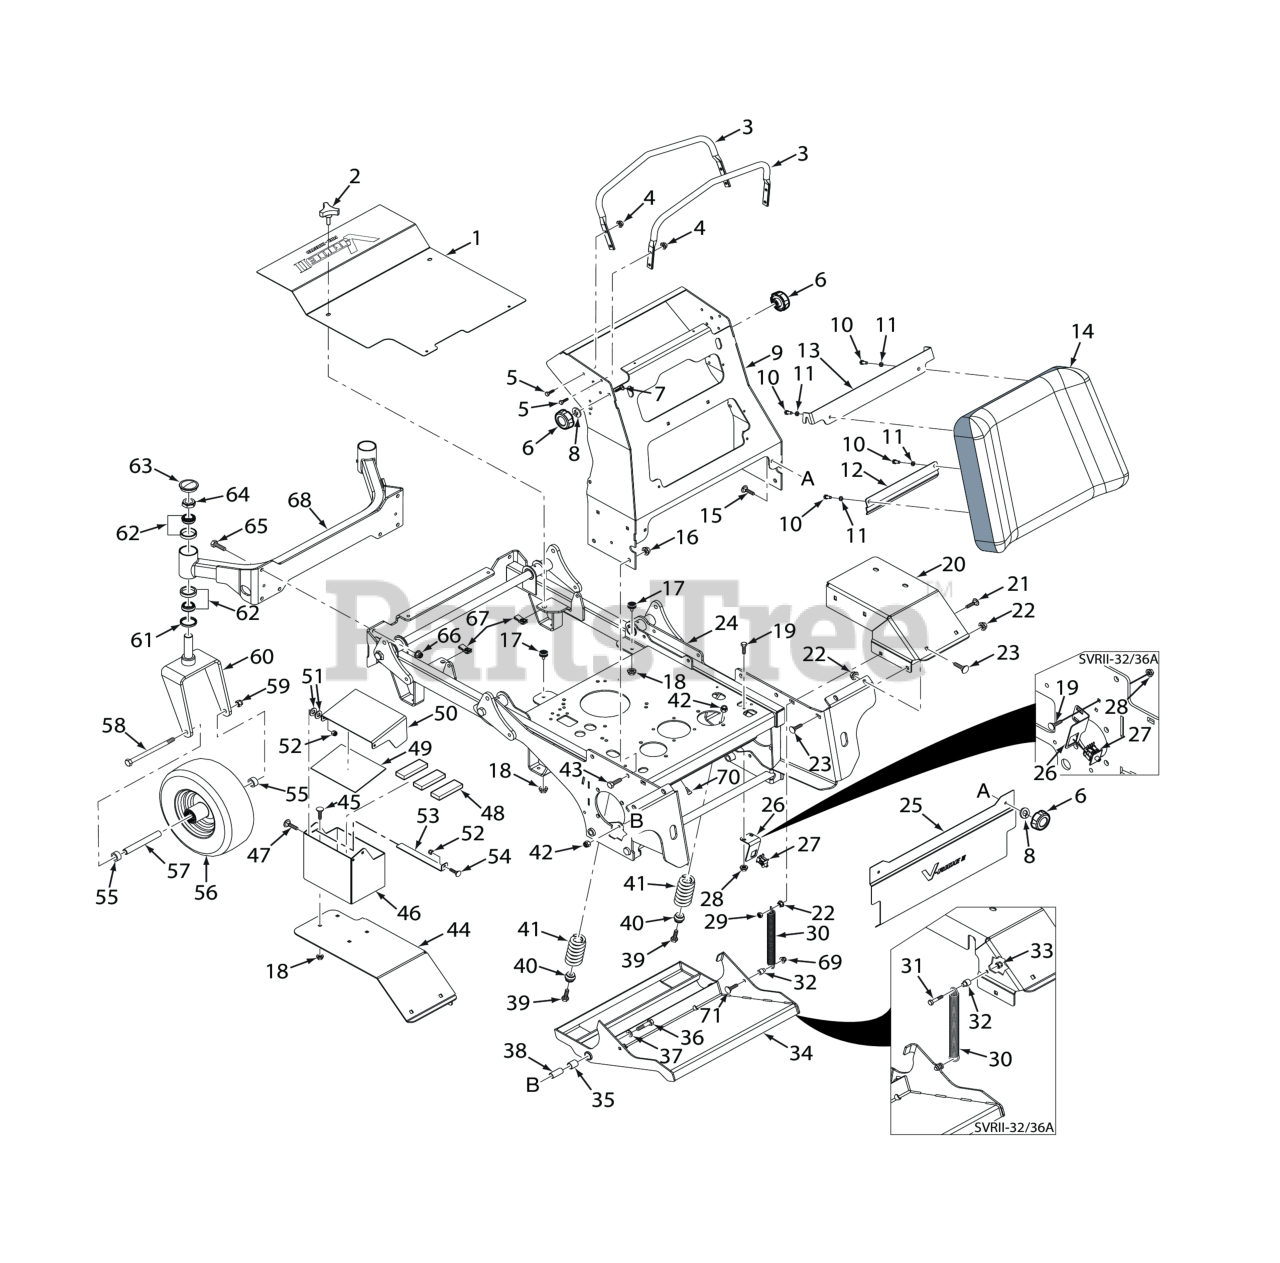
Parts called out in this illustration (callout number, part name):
1	Belt Cover w/Decals
2	Knob, w/stud 3/8-16 x 1-1/4"
3	Reference Bar
4	Nut, Serrated Flange 5/16-18 (Right Front Engine Mounting, Briggs and Kohler Only)
5	BOLT, SERRATED FLANGE HEX HEAD 5/16-18 X 3/4"
6	Knob, 5/16-18
7	Bolt, Carriage 5/16-18x1" (large frame units only)
8	Nut, Push-On 5/16-18
9	Handlebar Weldment, SVRII-36
10	BOLT, SERRATED FLANGE HEX HEAD 5/16-18 X 3/4"
11	Lockwasher, 5/16 (.317 x .586 x .078) Helical Spring
12	Bracket, Knee Pad - Lower
13	Bracket, Knee Pad - Upper
14	Operator Pad Assy, (32/36)
15	Bolt, 5/16-18 x .75 RHSN Carriage
16	Locknut, 1/2-13 Spiral Lock
17	Bumper, Rubber 5/16-18 x 5/8"
18	Nut, Serrated Flange 5/16-18 (Right Front Engine Mounting, Briggs and Kohler Only)
19	BOLT, HEX HEAD, 1/4-20 X 3/4 GR.5
20	Fender, RH - (32/36)
21	Bolt, Carriage 3/8-16 x 3/4"
22	NUT, 3/8-16 SERRATED FLANGE HEX HEAD
23	Bolt, Carriage 3/8-16 x 3/4"
24	Mainframe Assy. - SVRII- (32/36)
25	Guard, Foot
26	Switch Bracket, OPC Switch -SVRII-36
27	Switch, Double Pole OPC - SVRII-36
28	NUT, 1/4-20 SERRATED FLANGE HEX HEAD
29	Nut, Flange Elastic Stop Nut, 3/8-16
30	Spring,Counter Balance
31	Bolt, Hex Head 5/16-18 x 1-1/2" (Right Front Engine Mounting, Briggs and Kohler Only)
32	Spacer, Pump Dampener
33	HEX NUT, ELASTIC STOP LOCK, 5/16-18
34	Footplate Assy, SVRII-36
35	Bearing, .750 I.D. Plastic
36	Capscrew, Hex Head 3/8-16 x 2-1/2"
37	Flatwasher, 3/8" Special (.391 x .938 x .105)
38	Yoke, Front Caster Wheel
39	Bolt, Hex Head 3/8-16 x 1-3/4" (Kohler EFI)
40	Mount, Spring
41	Spring, Suspension Platform
42	HEX NUT, ELASTIC STOP LOCK, 3/8-16
43	Capscrew, 1/2-13 x 1" Serrated Flange Hex Head
44	Fender, LH - (32/36)
45	Bolt, 5/16-18 x .75 RHSN Carriage
46	Battery Box, Lower
47	BOLT, HEX HEAD, 1/4-20 X 3/4 GR.5
48	PAD, BATTERY SUPPORT
49	Insulation, Battery Cover (Gas Only)
50	Battery Box, Upper
51	Flatwasher, 1/4" (.312 x .750 x .065")
52	HEX, NUT, ELASTIC STOP LOCK, 1/4-20
53	Battery Box Latch
54	Serr. Fl. Hex Head CPSCR, 1/4-20 x 3/4"
55	Spacer, Caster Wheel
56	Caster Wheel Assembly, 11 x 4.0-5 (52V)
57	Sleeve, Caster Wheel (52V)
58	Bolt, Hex Head 1/2-13 x 6-1/2" (52V)
59	HEX LOCKNUT, ELASTIC STOP, 1/2-13
60	Yoke Weldment (32/36)
61	Seal, 2.00" O.D. x 1.625" Bore
62	Bearing Set
63	Cap, Grease
64	Nut, Elastic Stop 1.0"-14
65	BOLT, HEX HEAD, 7/16-14 X 1-1/4
66	Nut, 7/16-14 Flange Elastic Stop
67	U-Nut, 3/8-16
68	Caster Support Weldment (36)
69	Nut, Flange Head Elastic Stop 5/16-18
70	BUMPER, PLUG
71	Bolt, Carriage, 5/16-18 x 1½"
